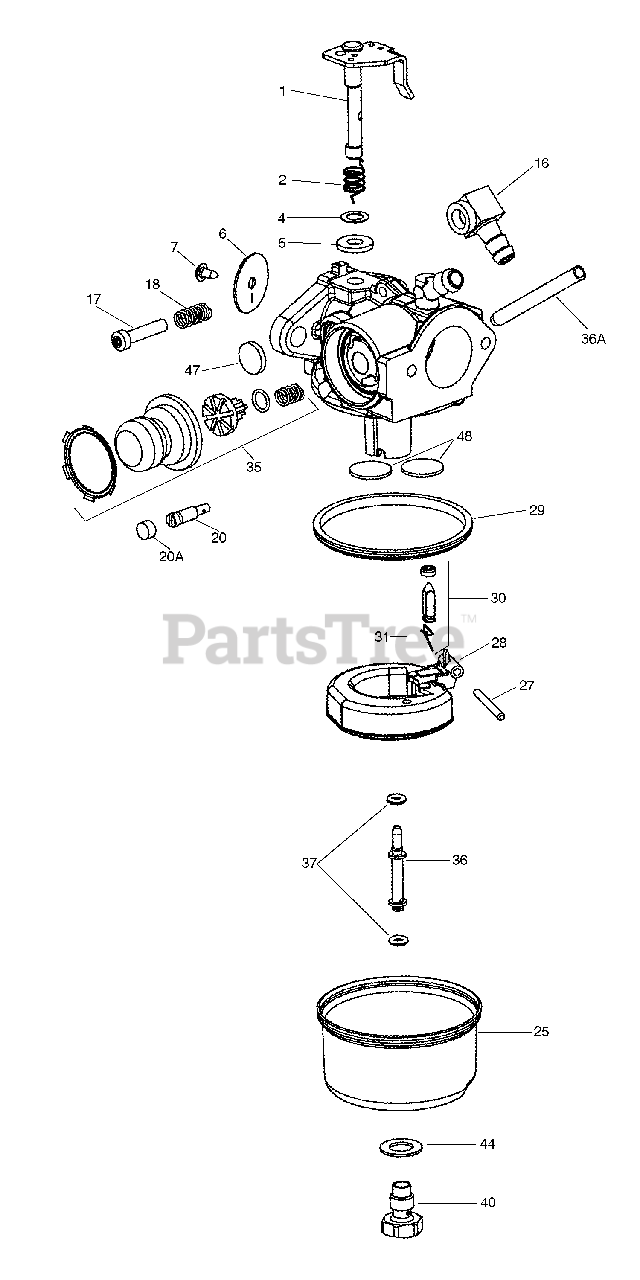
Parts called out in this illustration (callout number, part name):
1	Throttle Shaft & Lever Assembly
2	Throttle Return Spring
4	* Dust Seal Washer
5	* Dust Seal (Throttle)
6	Throttle Shutter
7	* Shutter Screw
16	Fuel Fitting
17	Throttle Crack Screw/Idle Speed Screw
18	Tension Spring
20	Idle Restrictor Screw
20A	Idle Restrictor Scrwe Cap (Black)
25	Float Bowl
27	* Float Shaft
28	Float (Plastic)
29	* Float Bowl "O" Ring
30	* Inlet Needle, Seat, & Clip (Incl. 31)
31	Spring Clip
35	Primer Bulb/Valve Repair Kit
36	Main Nozzle Tube
36A	Carburetor Tube
37	* "O" Ring, Main Nozzle Tube
40	High Speed Bowl Nut
44	* Bowl Nut Washer
47	* Welch Plug, Idle Mixture Well
48	* Welch Plug, Atmospheric Vent
60	Repair Kit (Incl. items marked PK in notes)
